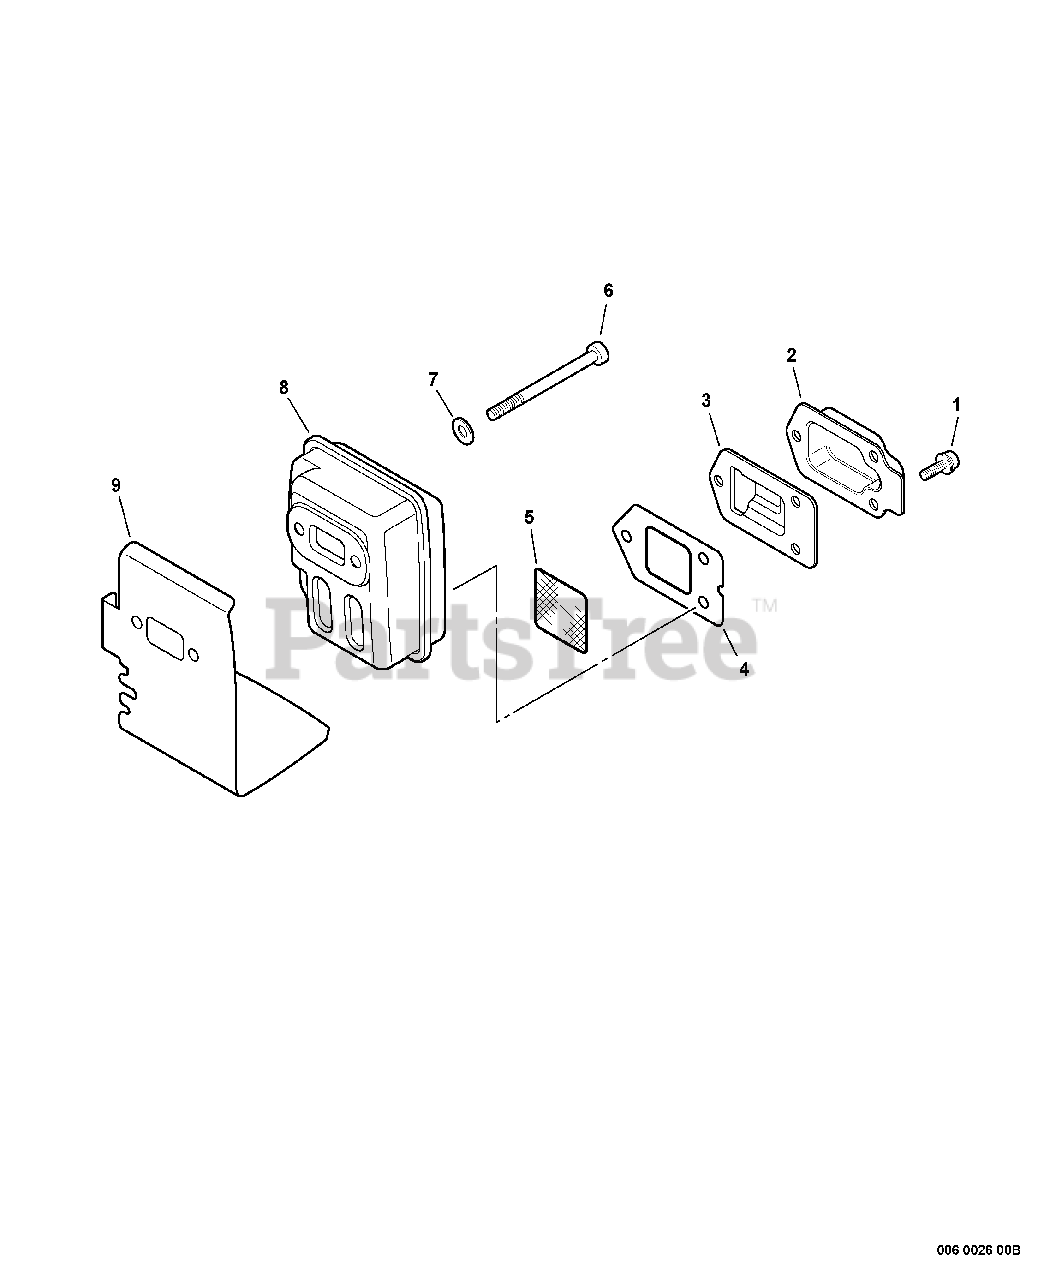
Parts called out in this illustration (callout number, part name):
1	SCREW - 4X10
2	GUIDE, EXHAUST - OUTER
3	GUIDE, EXHAUST - INNER
4	GASKET, EXHAUST
5	SCREEN, SPARK ARRESTOR
6	SCREW - 5X55
7	WASHER - 5
9	SHIELD, EXHAUST
